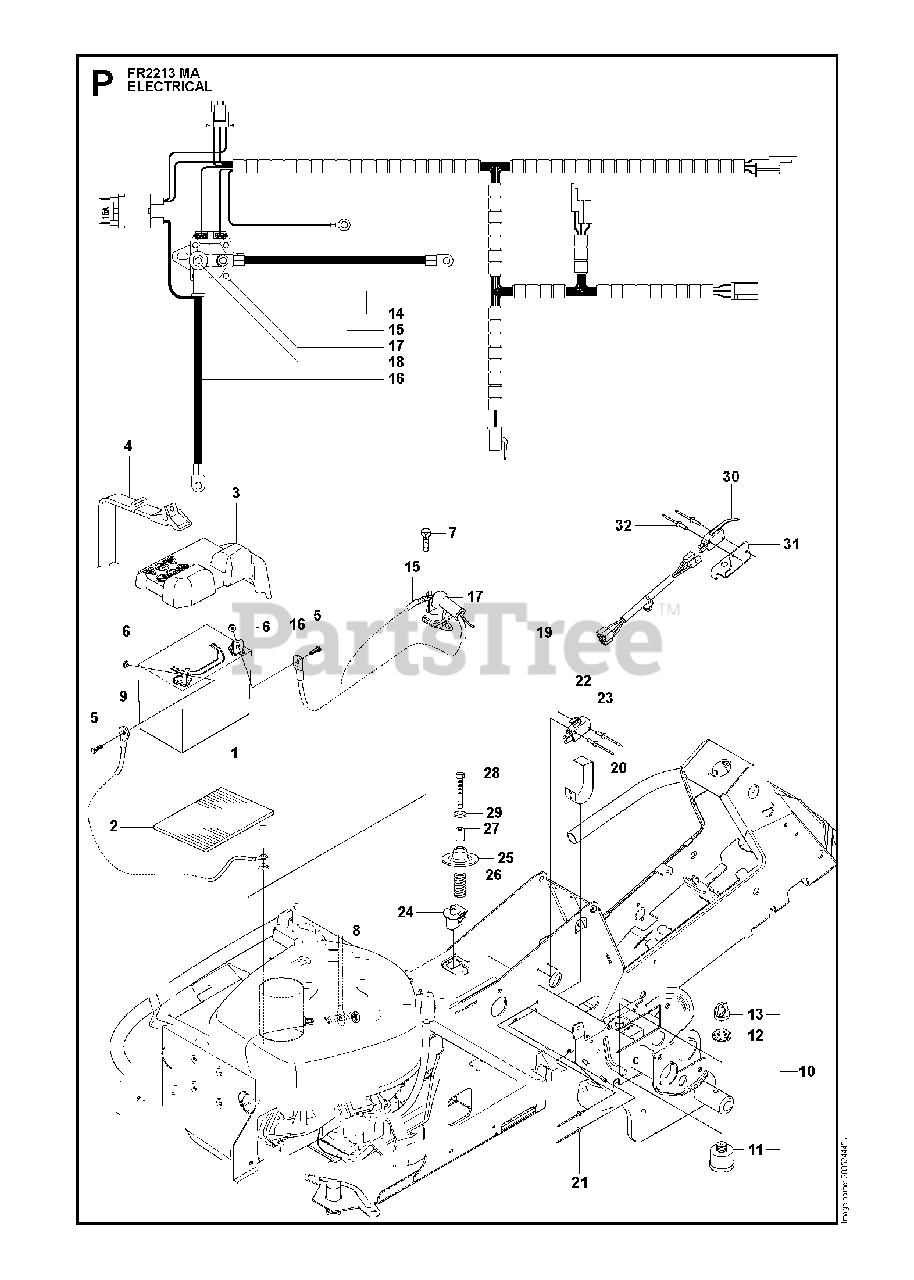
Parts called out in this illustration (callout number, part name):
5	SCREW EHHM
10	IGNITION SWITCH
11	IGNITION SWITCH
13	IGNITION KEY
22	%BRAKER
27	SPACER TUBE
28	SCREW
29	WASHER BRB 8.4X17
30	RP MICRO SWITCH
